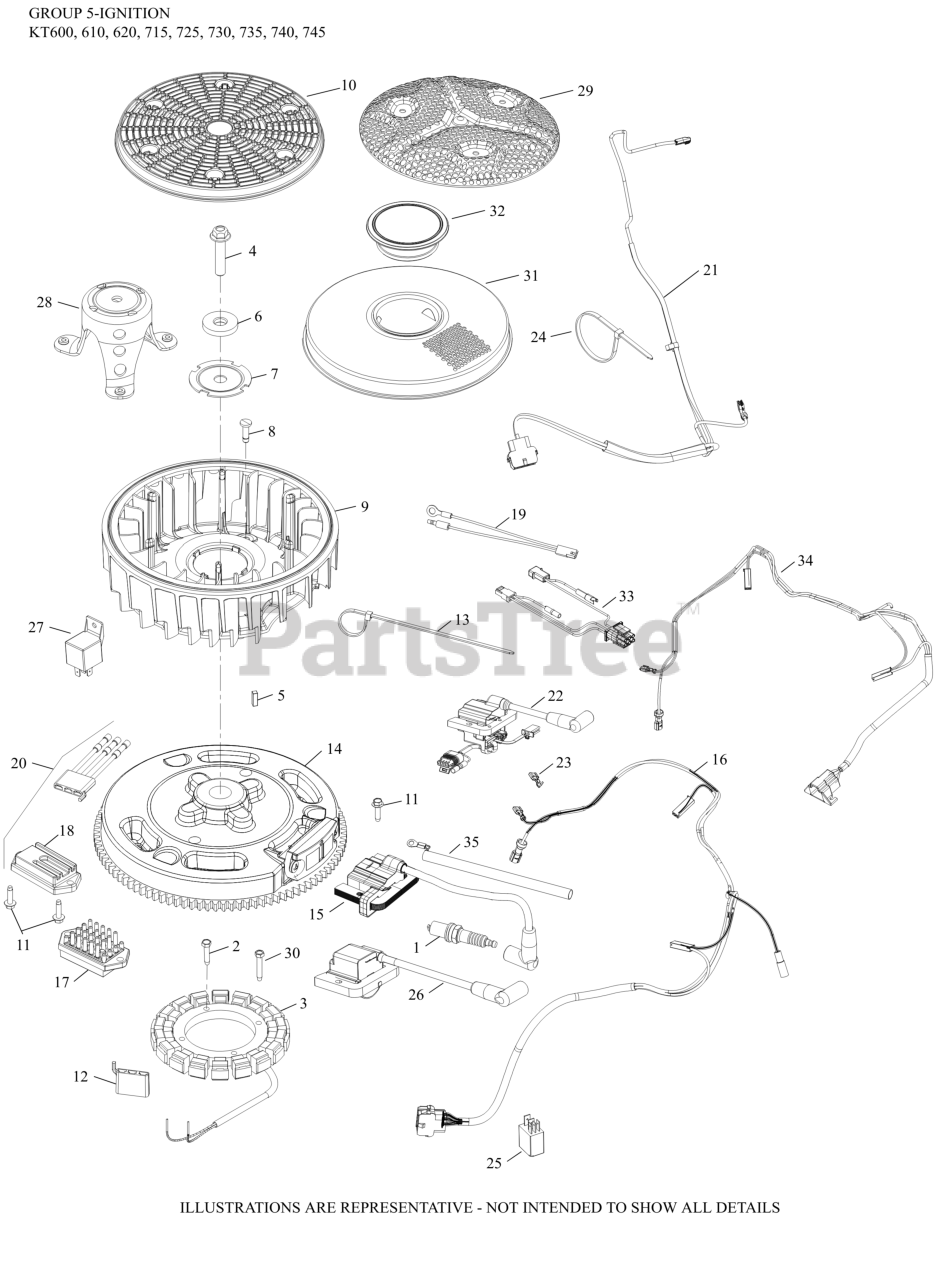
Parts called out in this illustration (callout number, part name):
1	PLUG, SPARK
2	SCREW, THREAD FORMING
3	KIT, 15 / 20 AMP STATOR
4	SCREW, HEX FLANGE
5	KEY, SQUARE
6	WASHER, FLAT
7	PLATE, FAN MOUNTING
8	RETAINER, FLYWHEEL FAN
10	SCREEN, GRASS
11	SCREW, THD FRM-USE 25 086 473-S
12	CONNECTOR
14	FLYWHEEL ASSEMBLY
15	MODULE, CDI IGNITION
16	HARNESS, WIRING ASSEMBLY
18	REGULATOR/RECTIFIER 12/15A HALF-WAVE STD
